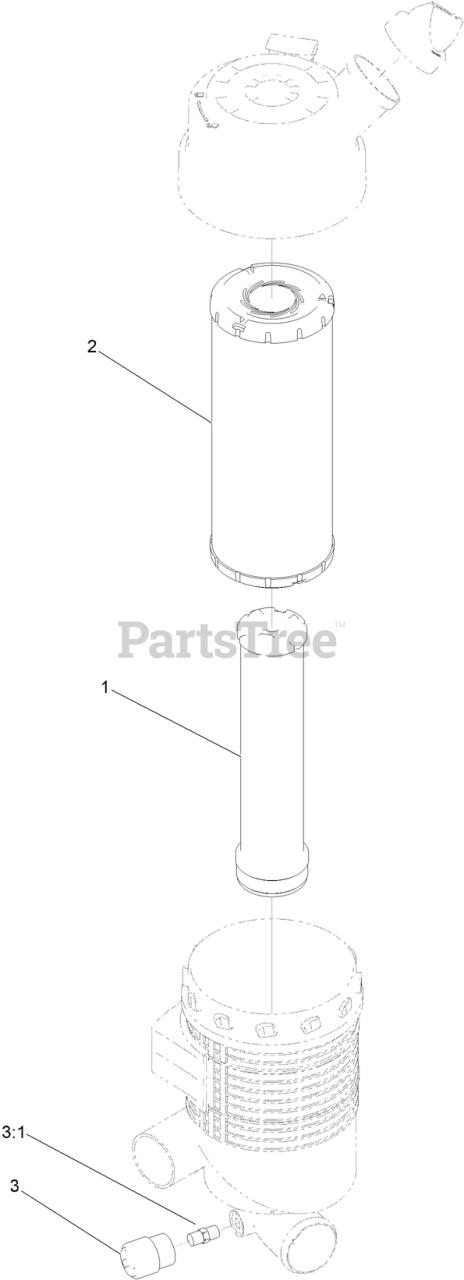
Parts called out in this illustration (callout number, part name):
1	ELEMENT-SAFETY, 5 INCH
2	FILTER-AIR
3	INDICATOR
3:1	ADAPTER-INDICATOR
